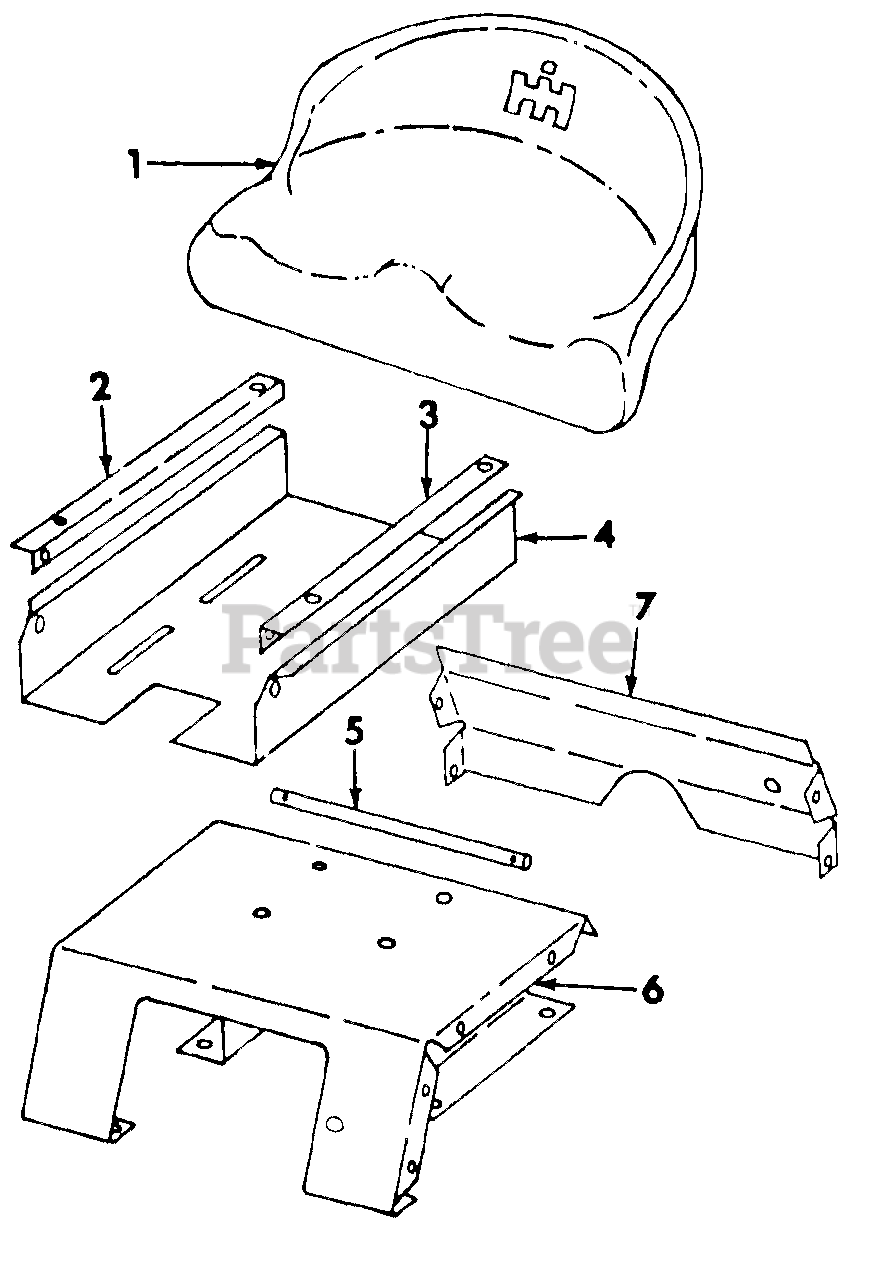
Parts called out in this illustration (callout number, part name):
1	Seat Assy
2	Rail, Seat Support RH
3	Rail, Seat Support LH
4	Support, Seat
5	Pin, Seat Pivot
6	Cover & Seat Support Assy, Rear Frame
7	Panel Assy, Rear Frame Cover Back
